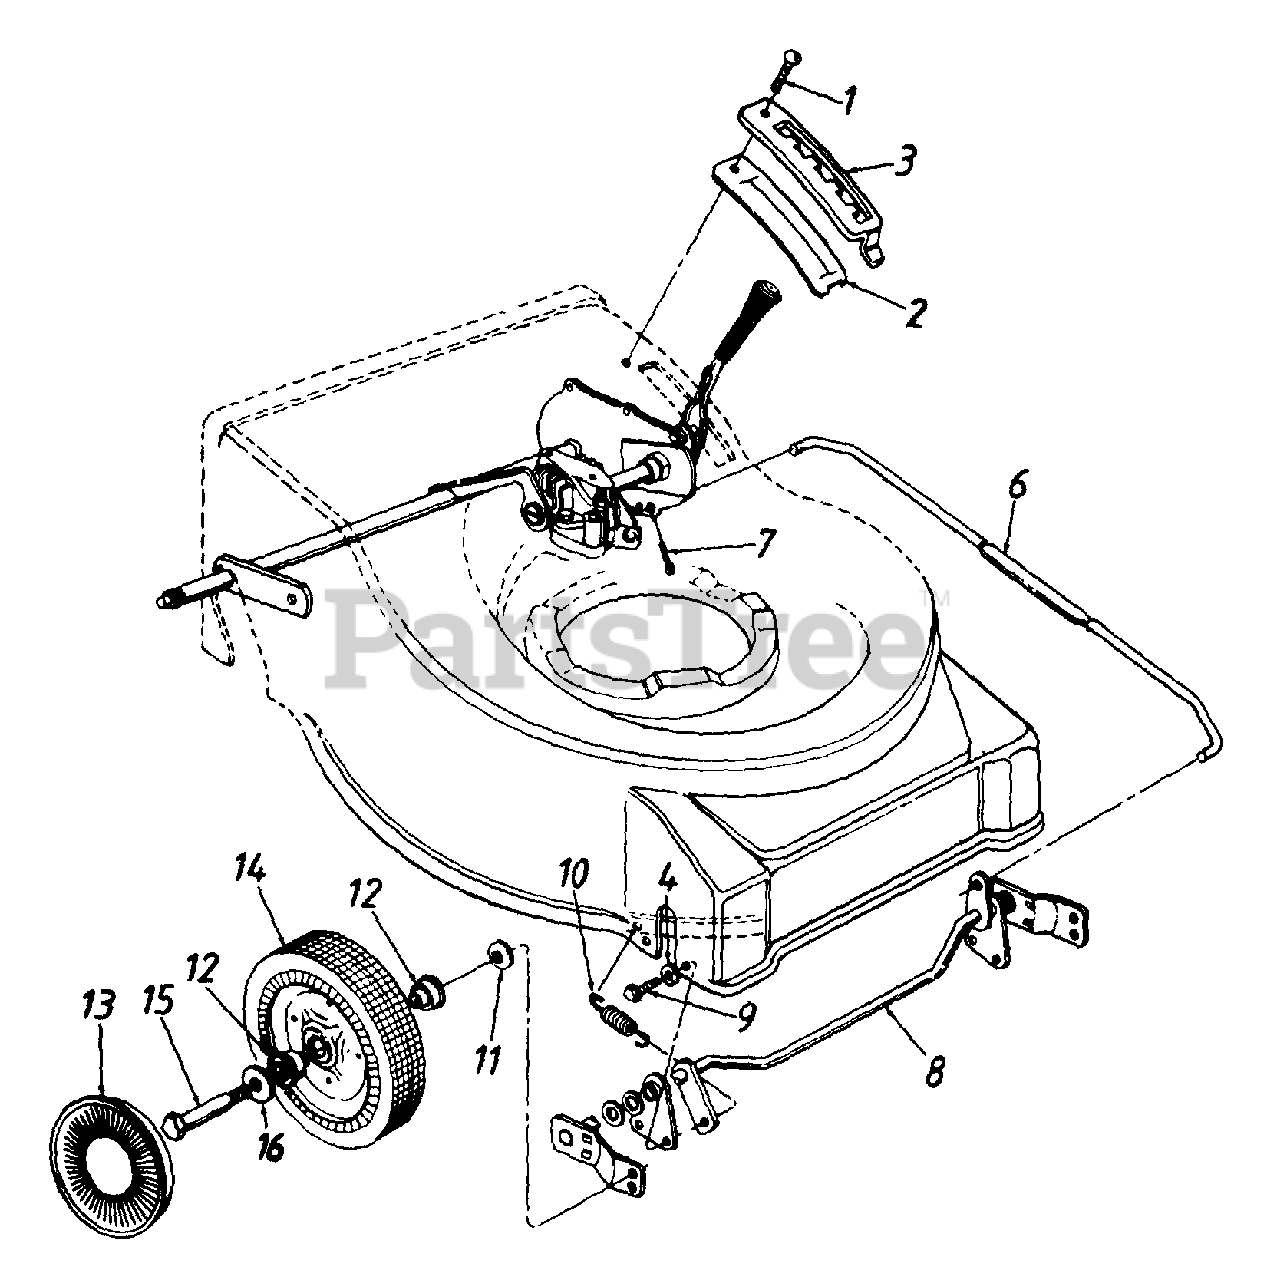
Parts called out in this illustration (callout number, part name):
1	Torx Mach. AB-Tap Scr. 1/4 x .62" Lg.
2	Height Adjustment Support
3	Height Adjustment Plate
4	L-Wash. 1/4" I.D.
6	Height Adj. Connecting Rod
7	Cotter Pin 3/32" Dia.
9	Hex L-Wash. Hd. AB-Tap Scr. 1/4 x .38" Lg.
10	Extension Spring 2.39" Lg.
11	Bell-Wash..380" I.D. x .88"
12	Ball Bearing 1/2" I.D.
13	Hub Cap (See Above)
14	Wheel Ass'y. Comp.- Front
15	Shld. Bolt .498" Dia. x 1.45"
16	Wave Wash..51" I.D. x .78"
